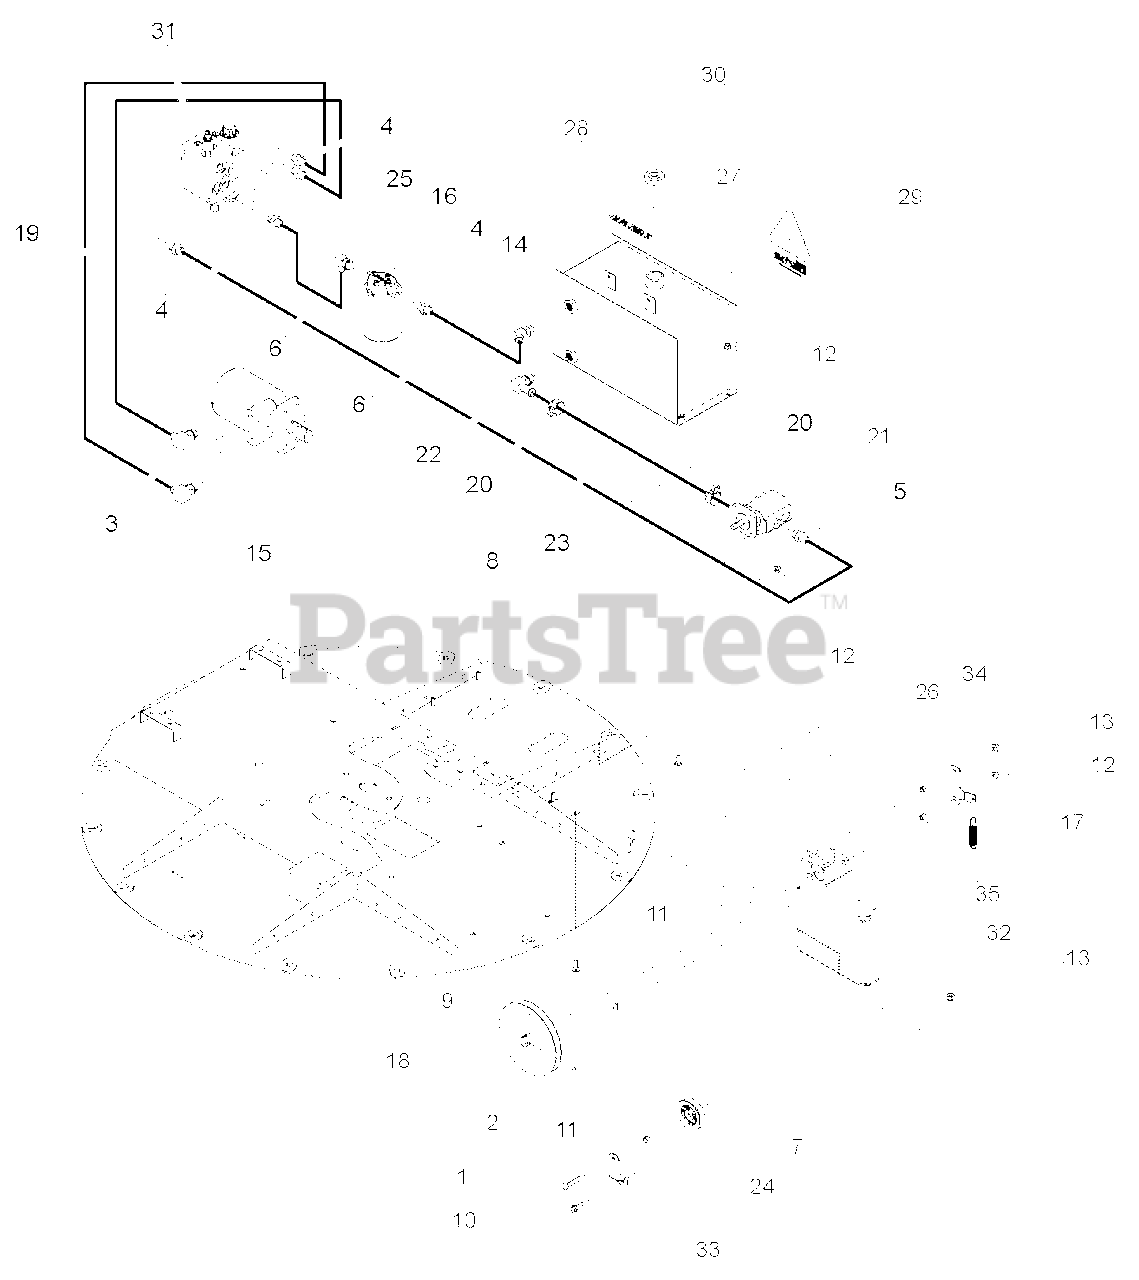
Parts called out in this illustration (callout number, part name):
1	BOLT, 3/8 X 2-1/4 HEX GR5 ZP
2	SET SCREW, HSC 1/4 -20X -3/8 CUP
3	ADAPTER, -10MORING/-8MJIC 90 DEG
4	ADAPTER, -8MORING/-8MJIC
5	ADAPTER, -10MORING/-8MJIC
6	HOSE ASSEMBLY, 8FMJIC/8FMJIC SW X 32"
7	IDLER, INSIDE
8	HOSE ASSEMBLY, 8FJIC90 SW X 8FJIC SW 54"
9	BOLT, 3/8 X 1" GR5 CRG NC ZP
10	BOLT, 5/16 X 1 FLANGE NC
11	BOLT, 5/16 X 1" GR5 CRG ZP
12	NUT, 5/16-18 NYLOCK-FLANGE
13	NUT, 3/8-16 NYLOCK FLANGE
14	ADAPTER, -10MORING/-8MJIC 45 DEG
15	MOTOR, 45 CU IN HYDRAULIC
16	ASSEMBLY, HYDRAULIC FILTER
17	SPRING, 3/4" OD EXTENSION
18	PULLEY, 7.5 OD X 1/2 IN BORE
19	HOSE ASSEMBLY, -8FMJIC/-8FMJIC90 X 61
20	CLAMP, 1-5/32 TO 7/32 OD RANGE T-BOLT
21	PUMP, 2 STAGE CW HI/LO 0.605 DISP.
22	ADAPTER, -10 MORING/.75 90 DEG HOSE
23	HOSE, .75 X 19.75 100R4
24	BUSHING
25	ADAPTER, -8MORING/-8MJIC 90 DEG
26	SPACER, IDLER PIVOT
27	ASSEMBLY, HYDRAULIC TANK SERVICE PART
28	DECAL, HYDRAULIC FLUID
29	DECAL, CHIP IT (WHITE)
30	CAP, HYDRAULIC W/ DIPSTICK
31	ASSEMBLY, HYDRAULIC FEED FLOW VALVE W/ PS
32	WELDMENT, PUMP MOUNT
33	BRACKET, IDLER MOUNT
34	PLATE, IDLER MOUNT
35	SPACER, 1/2 OD X 14 GA X .49
